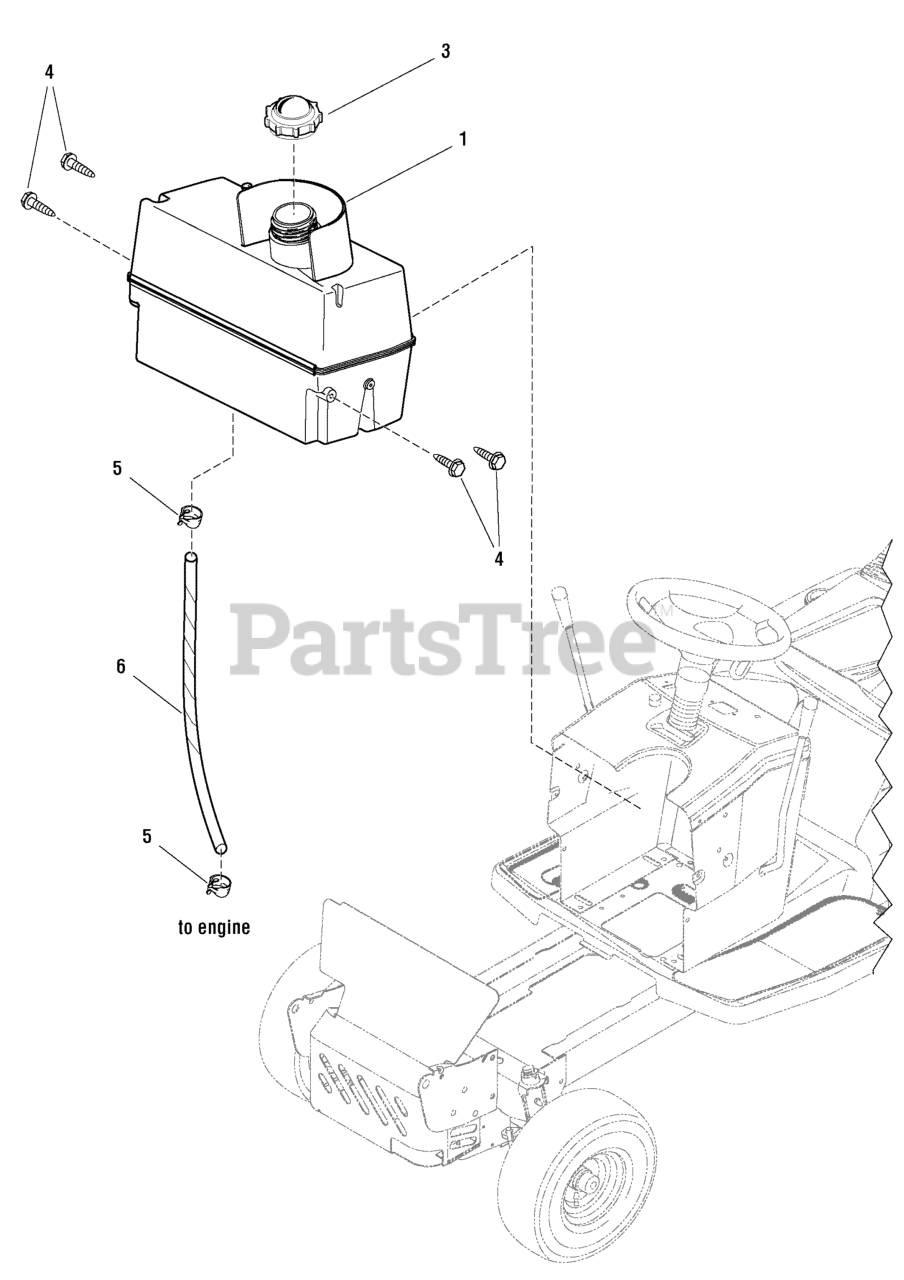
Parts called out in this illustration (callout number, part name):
1	FUEL TANK W/ CAP, 2.8 Gallon, Murray
3	CAP, Fuel Tank
4	SCREW, Thread Forming, 3/16-15 x 7/8
5	HOSE CLAMP
6	HOSE, FUEL, Low Perm, 17 in
